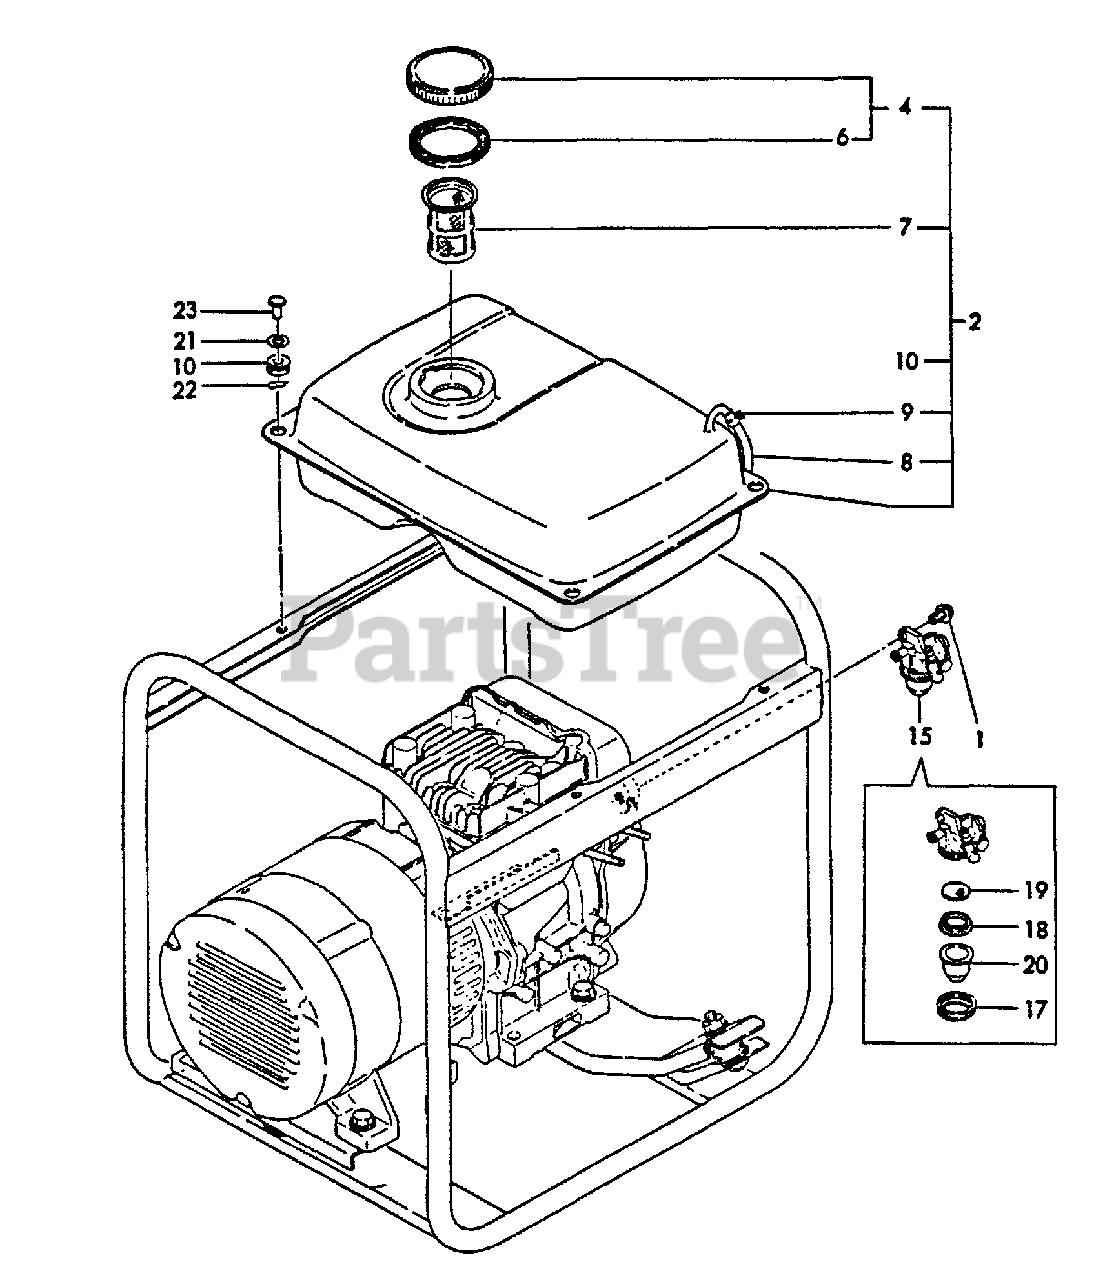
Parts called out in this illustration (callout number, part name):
1	BOLT - 6×8 -- PLATED
2	FUEL TANK ASSY
4	CAP ASSY
6	GASKET
7	STRAINER, FUEL
8	PIPE, FUEL GAUGE
9	CLAMP, HOSE - 9
10	GROMMET
15	COCK ASSY, FUEL
17	RETAINER
18	GASKET
19	FILTER, FUEL
20	BOWL, STRAINER
21	WASHER
22	PIN - 6 -- SNAP
23	PIN 6×14
